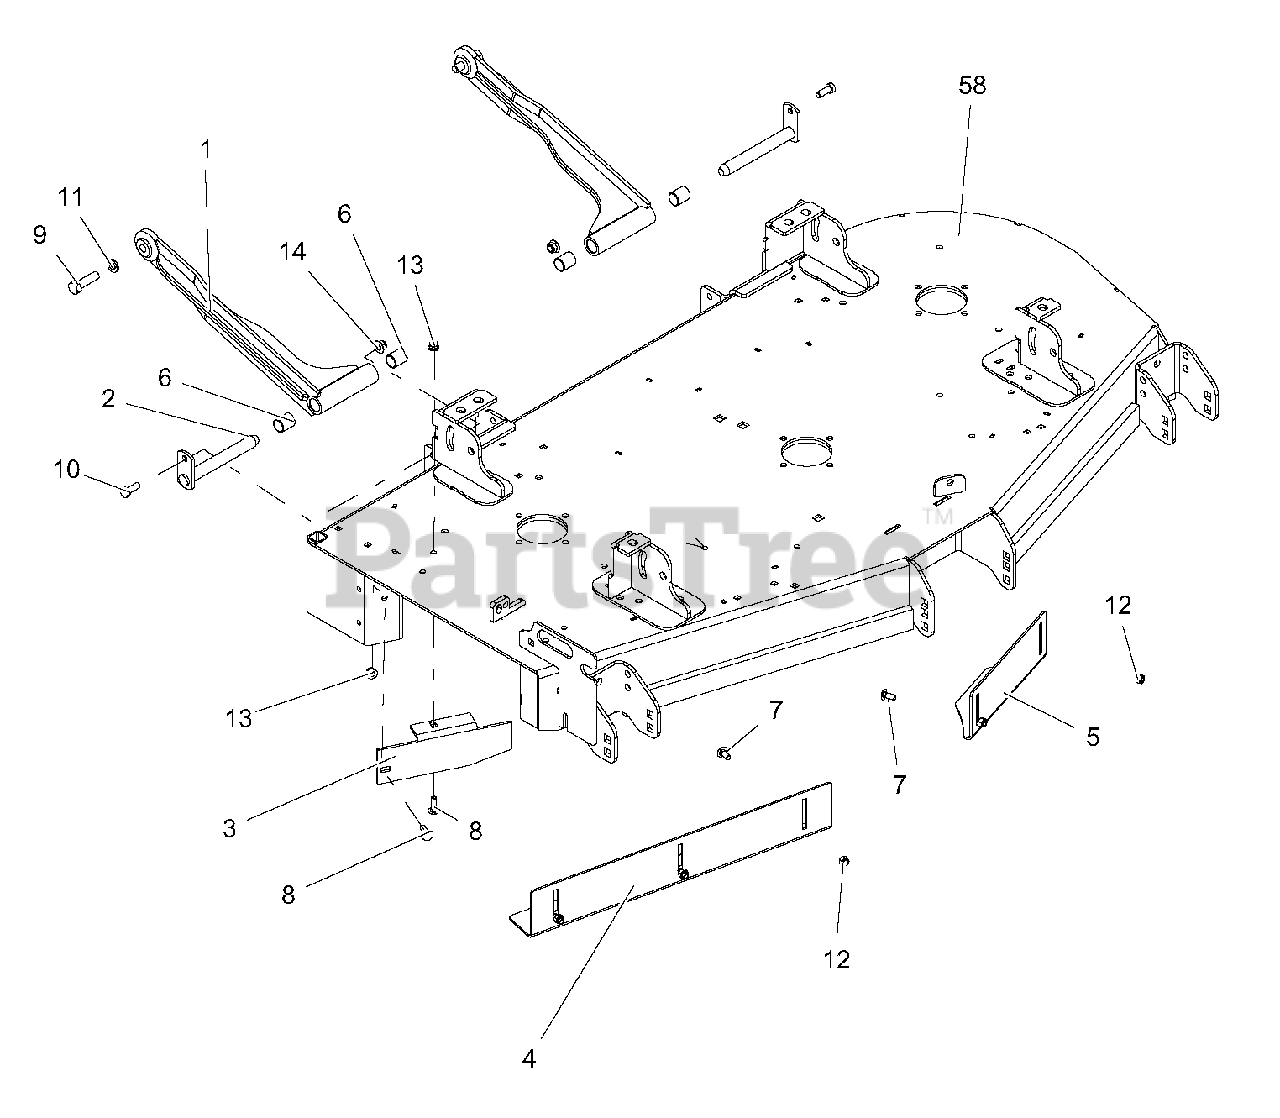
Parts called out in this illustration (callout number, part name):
1	WMT, DECK STABILIZER ARM-BLACK
2	WLDMT, MOWER MTG. PIN
3	BAFFLE, 52" DISCHARGE-RED
4	BAFFLE, 52" RH VACUUM-BLACK
5	BAFFLE, 52" LH VACUUM-BLACK
6	BRG, .75 X .875 X 1.00
7	BLT-RDHDSQNK .31-18X.75 G5 YWZC
8	BLT-RDHDSQSHNK .31-18X1.00 G5 Y
9	BLT-HEX .50-13X1.75 GR5 YWZC
10	BLT-HEX .38-16X1.00 GR5 YWZC
11	WSHR-LK .50X.125 REG YWZC
12	NUT-LK-NYL .312-18 YWZC
13	NUT-LK-NYL-FLG .31-18 YWZC
14	NUT-LK-NYL-FLG .38-16 YWZC
58	WLDMT, 52" PT200 SIDE DISCHARGE DECK-RED
